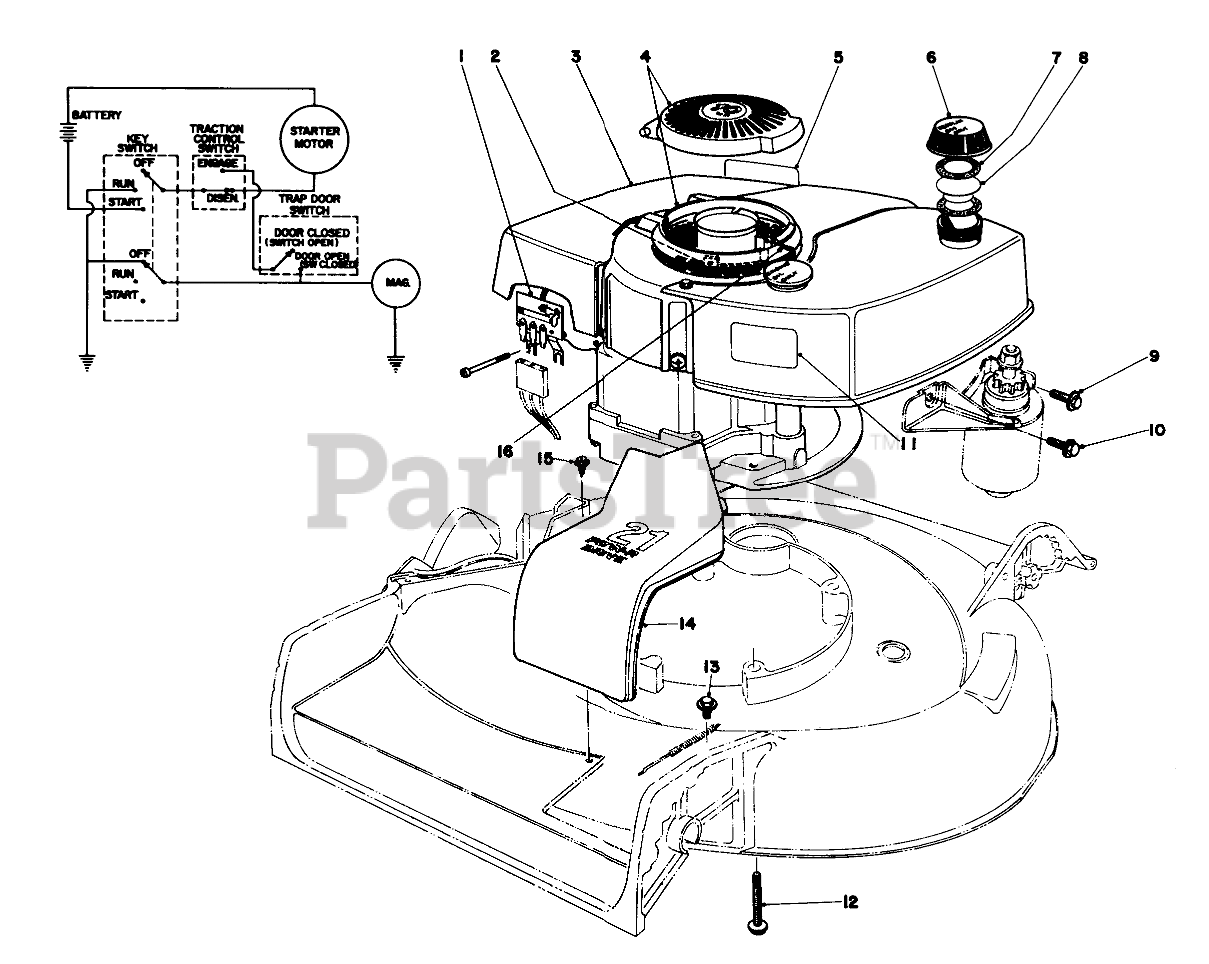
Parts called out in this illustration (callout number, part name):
1	SWITCH & TERM BLK CVR
2	WIRE CLIP
3	Engine
4	Cover
5	Decal Maintenance
6	Gas Cap (Incl. Ref. #7 & 8)
7	GASKET
8	GAS CAP BAFFLE
9	SCREW
10	Screw
11	Decal
12	3/8-16 X 2-3/4 CAPSCR
13	SCREW-HWHTF
14	Cover Belt Drive
15	SCREW
16	SPRING PIN
